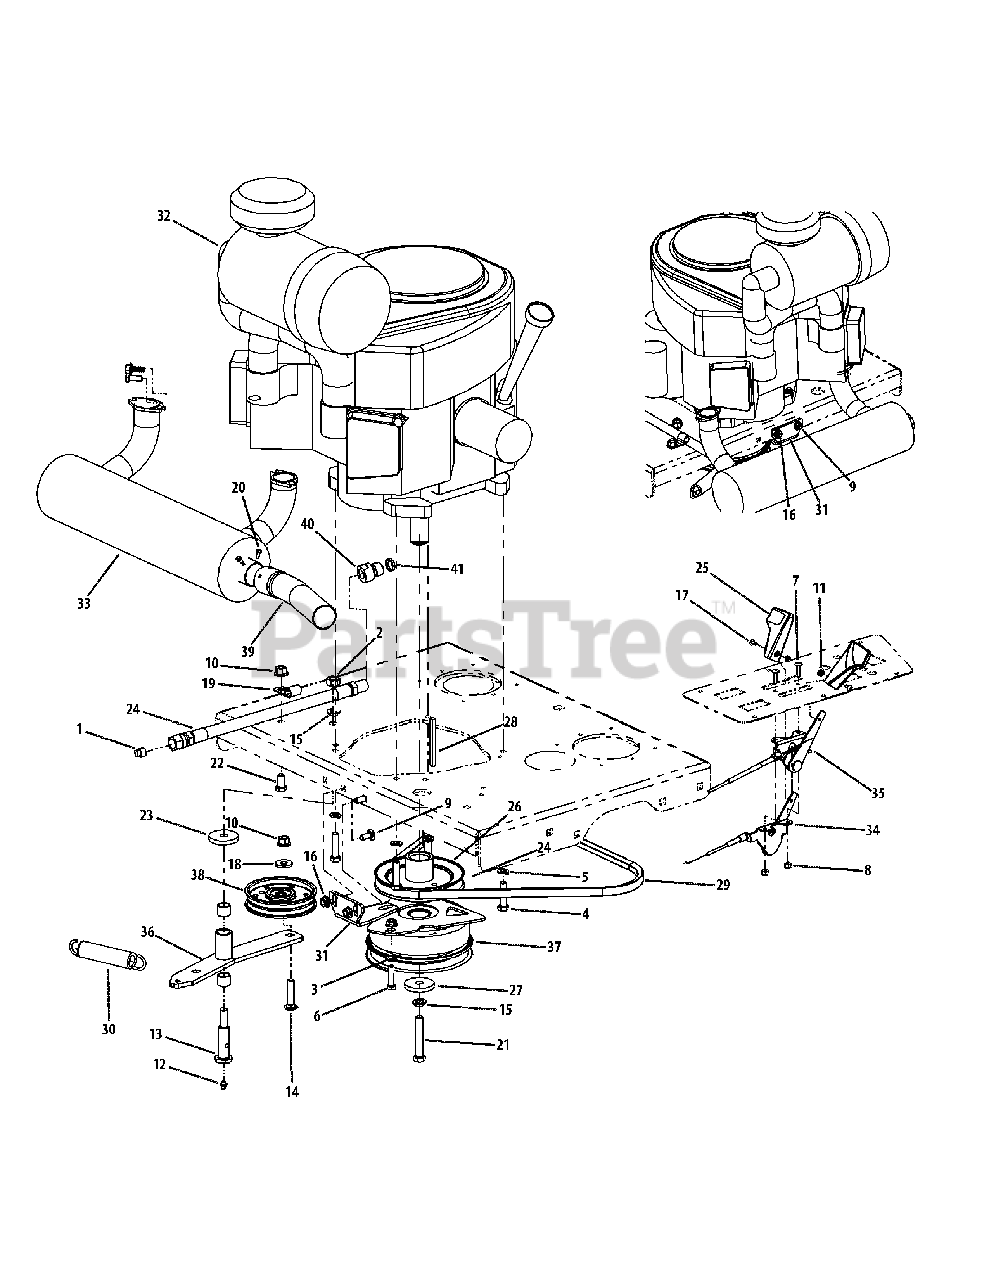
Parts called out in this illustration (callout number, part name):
1	Pipe Plug, 3/8 NPT
2	Hex Nut, 7/16-14
3	Flat Washer, 5/16
4	HHCS, 3/8-16, 1-1/2
5	Lock Washer, 3/8
6	HHCS, 5/16-18 x 1-1/4
7	Machine Screw, 10-32 x 5/8
8	Lock Nut, Nylon Insert, 10-32
9	Carriage Bolt, 5/16-18 x .75
10	Flange Lock, Hex Nut, 3/8-16
11	Nut Washer, W/Star, 8-32
12	Grease Fitting, 1/4-28 x 3/16
13	Shoulder Screw, 7/16-14
14	Hex Carriage Screw, 3/8-16, 1.75
15	Lock Washer, 7/16
16	Hex Flange Lock Nut, 5/16-18
17	Machine Screw, 8-32, .375
18	Flat Washer, .406 ID, 1.0 OD, .105
19	Clip, Heat Shield Cable
20	Screw, #10-16 x 0.500
21	Cap Screw, 7/16-20 x 2.50
22	Hex Cap Screw, 3/8-16, .750
23	Flat Washer, 7/16 ID x 1.75 OD x .25
24	Oil Drain Hose
25	Control Throttle Knob
26	Pump Drive Pulley
27	Flat Washer, 7/16 ID x 1.75 OD x .25
28	Key, 1/4 x 1/4 x 3
29	V Belt, A Section x 50.0
30	Extension Spring, .98 OD x 5.00
31	Retainer Clutch Assembly, Ogura
32	31HP Twin Engine, Kawasaki
33	Muffler Accessory, Kawasaki
34	Throttle, Control Cable
35	Choke, Control Cable
36	Engine Idler Arm includes:
36	Bearing
37	Clutch Brake, 1.125 ID
38	Flat Pulley with Flanges
39	Muffler Accessory Exhaust Tube
40	Oil Drain Adapter
41	O-Ring Fitting
